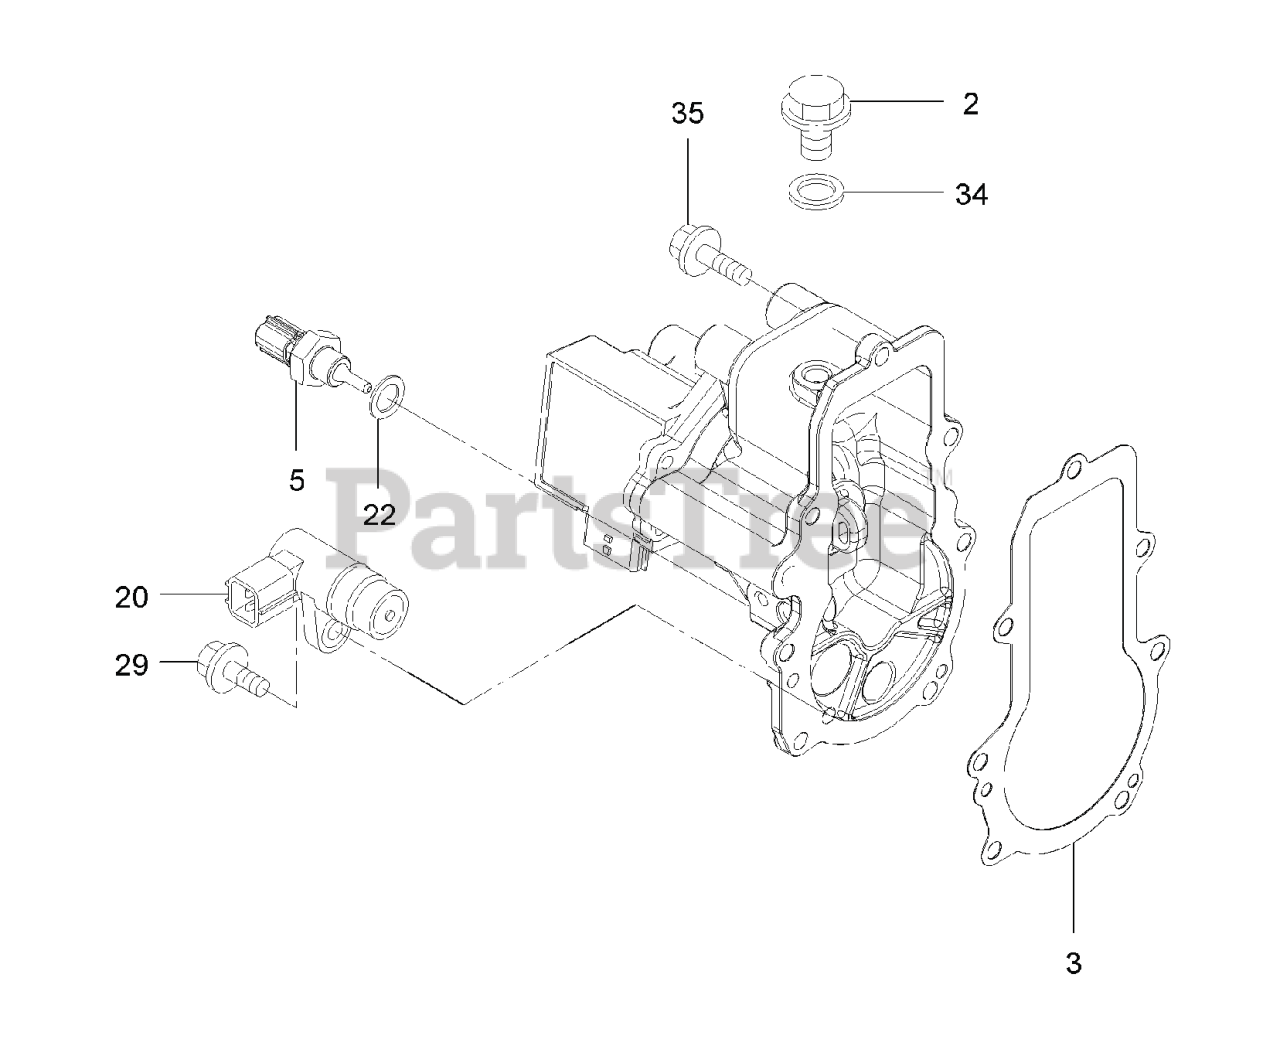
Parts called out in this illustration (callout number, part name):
5	SENSOR-OIL TEMP
22	WASHER-SEAL
34	WASHER-SEAL
